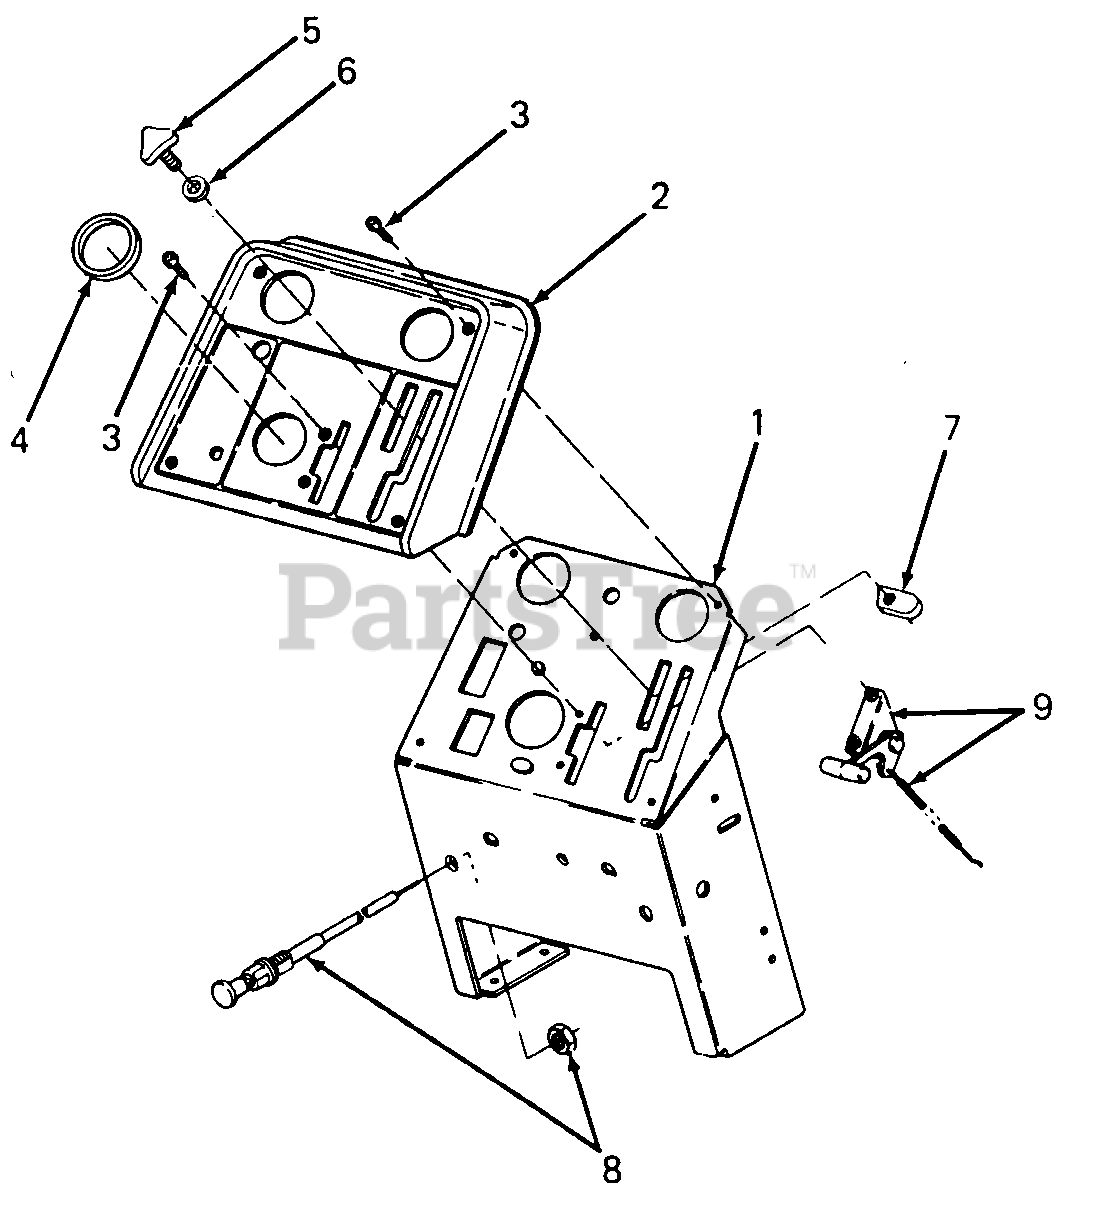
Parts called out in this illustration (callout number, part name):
2	Panel, Instrument
3	Screw, Pan Hd Cutting, #10-24 X .75 Lg
4	Grommet, Instrument Panel
6	Washer, Flat, .266 X .625 X .035 Thk
7	Stop, Handle Detent
8	Choke Cable w/Nut
9	Control, Throttle
